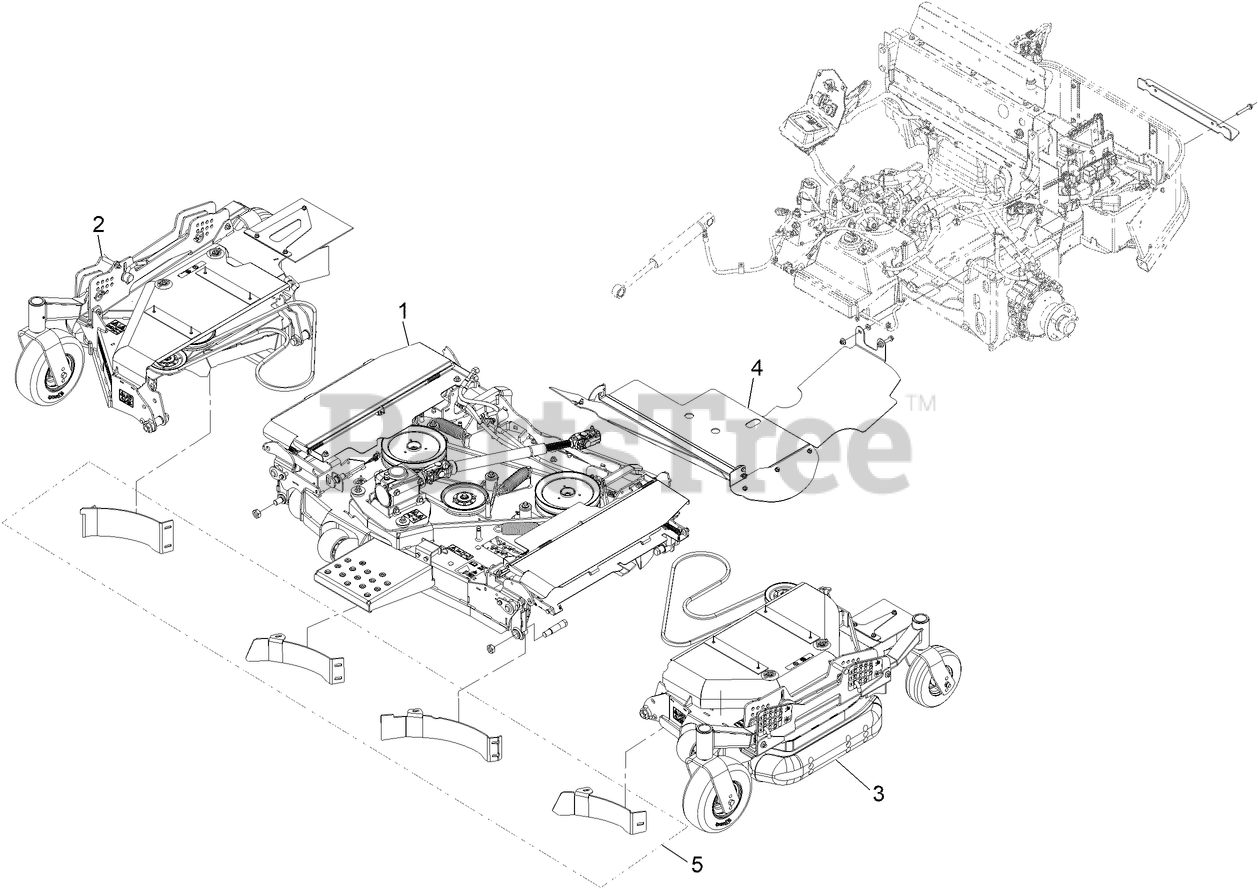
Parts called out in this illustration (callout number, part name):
1	ASM-Deck, Ctr 96E
2	ASM-Deck, RH Wing 96E
3	ASM-Deck, LH Wing 96E
4	Discharge Tunnel ASM
5	KIT-96RD MULCH
